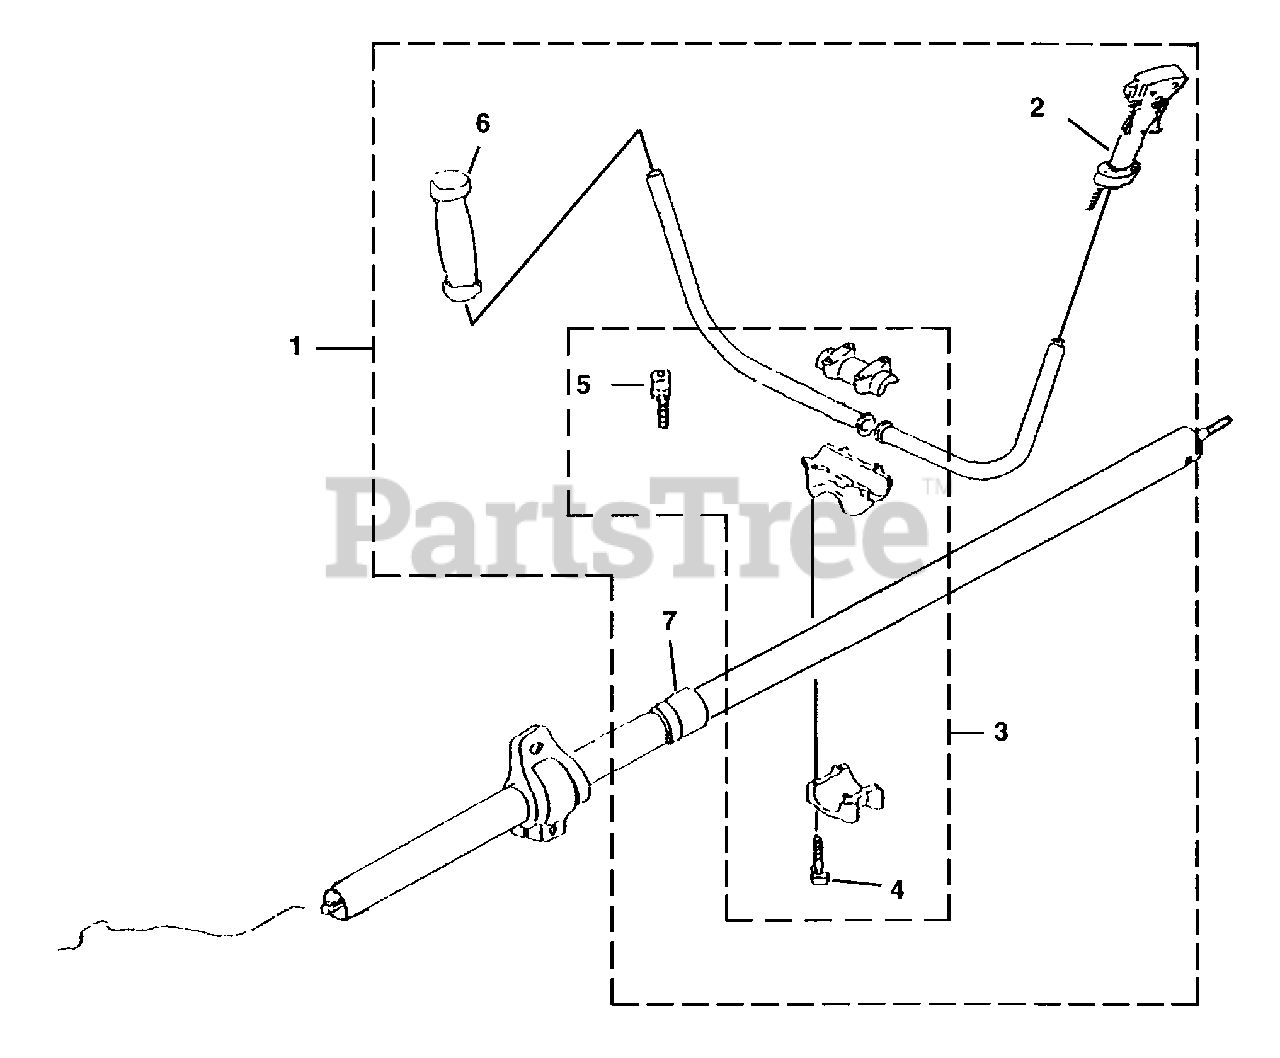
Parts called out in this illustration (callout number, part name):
1	HANDLE ASSEMBLY
2	CONTROL LEVER ASSEMBLY
3	HANDLE, BRACKET ASSEMBLY
4	SCREW
5	SCREW
